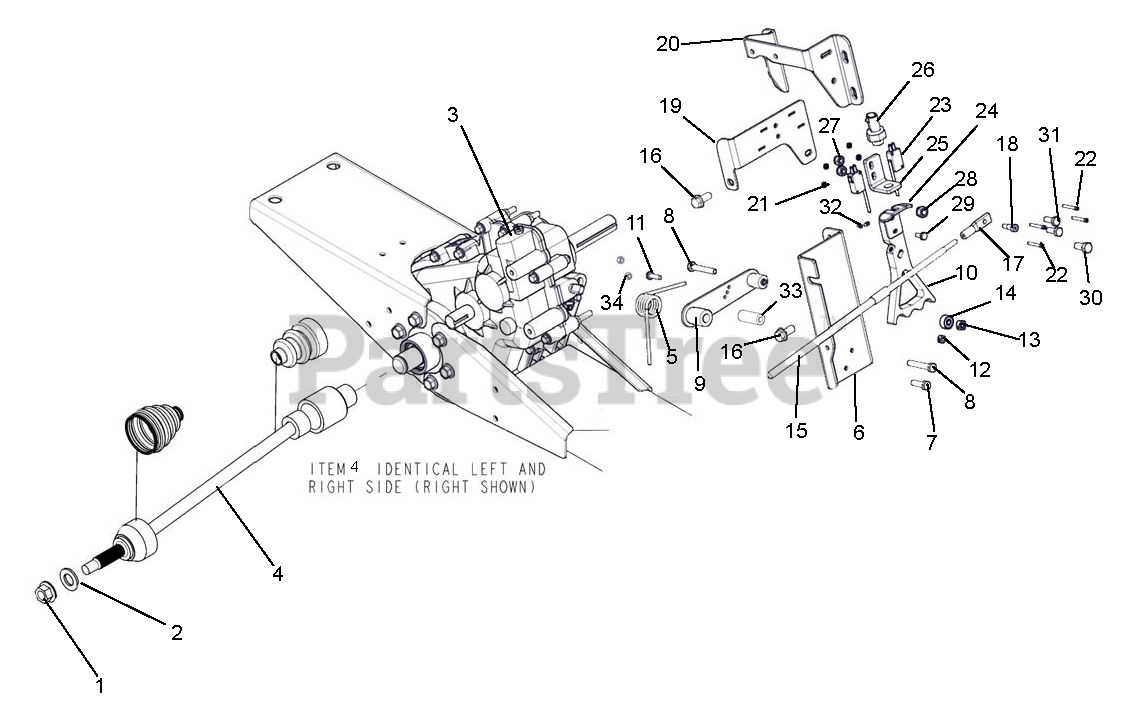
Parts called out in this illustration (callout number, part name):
1	NUT HEX FLG T LCK M16X1.5 PLT
2	@WSHR-FL-STL.812X1.50X.135YWZC
3	TRANSAXLE, DANA
4	REAR AXLE SHFT ST, 24T INT.SPL
5	SPRING, TORSION, 1.058 X .777
6	BRACKET, SHIFT
7	@BLT-HEX .25-20X1.00 GR5 YWZC
8	@BLT-HEX .25-20X1.75 GR5 YWZC
9	FOLLOWER WLDT
10	SHIFT CAM, TRANS SIDE
11	@SCR-MCH 10-24X.75 HWH YWZC
12	LOCKNUT, 10-24 CENTER Y
13	@NUT-LK-CTR .25-20 YWZC
14	BRG, BAL .250X.688X.313
15	SHIFT CABLE (DASH)
16	HFS 5/16-18X3/4 GR5
17	CABLE END
18	BLT-SHLDR .25X.375
19	BRACKET,MNT,SWITCH
20	BRACKET, CVT COVER TO TRANS.
21	NUT-HEX 4-40 YWZC GR5
22	HSHCS #4-40X1
23	PARK BRAKE MICRO-SWITCH
24	BRACKET, SWITCH ACTIVATING
25	MOUNT, PLUNGER SWITCH
26	SWITCH, NEUTRAL
27	@NUT-LK-NYL .250-20 YWZC
28	@NUT-LK-NYL .312-18 YWZC
29	@SCR-MCH 10-24X.50 HWH YWZC
30	@BLT-HEX .31-18X.75 GR5 YWZC
31	@BLT-HEX .25-20X.75 GR5 YWZC
32	SCR-SET .25-28X.375 SK CUP
33	BUSHING, 0253 X .495 X 1.0625
34	@NUT-LK-CTR .25-20 YWZC
